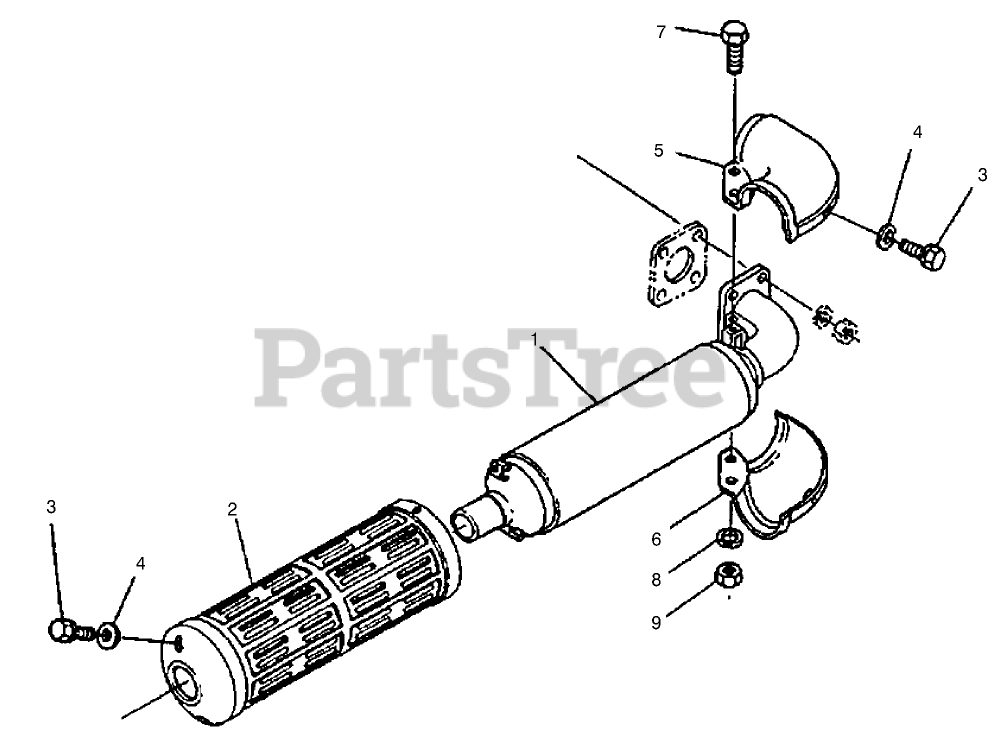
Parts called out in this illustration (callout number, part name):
1	MUFFLER
2	COVER, MUFFLER
4	WASHER-PLAIN
5	COVER, MUFFLER FLANGE
6	COVER, MUFFLER FLANGE
8	WASHER-SPRING
